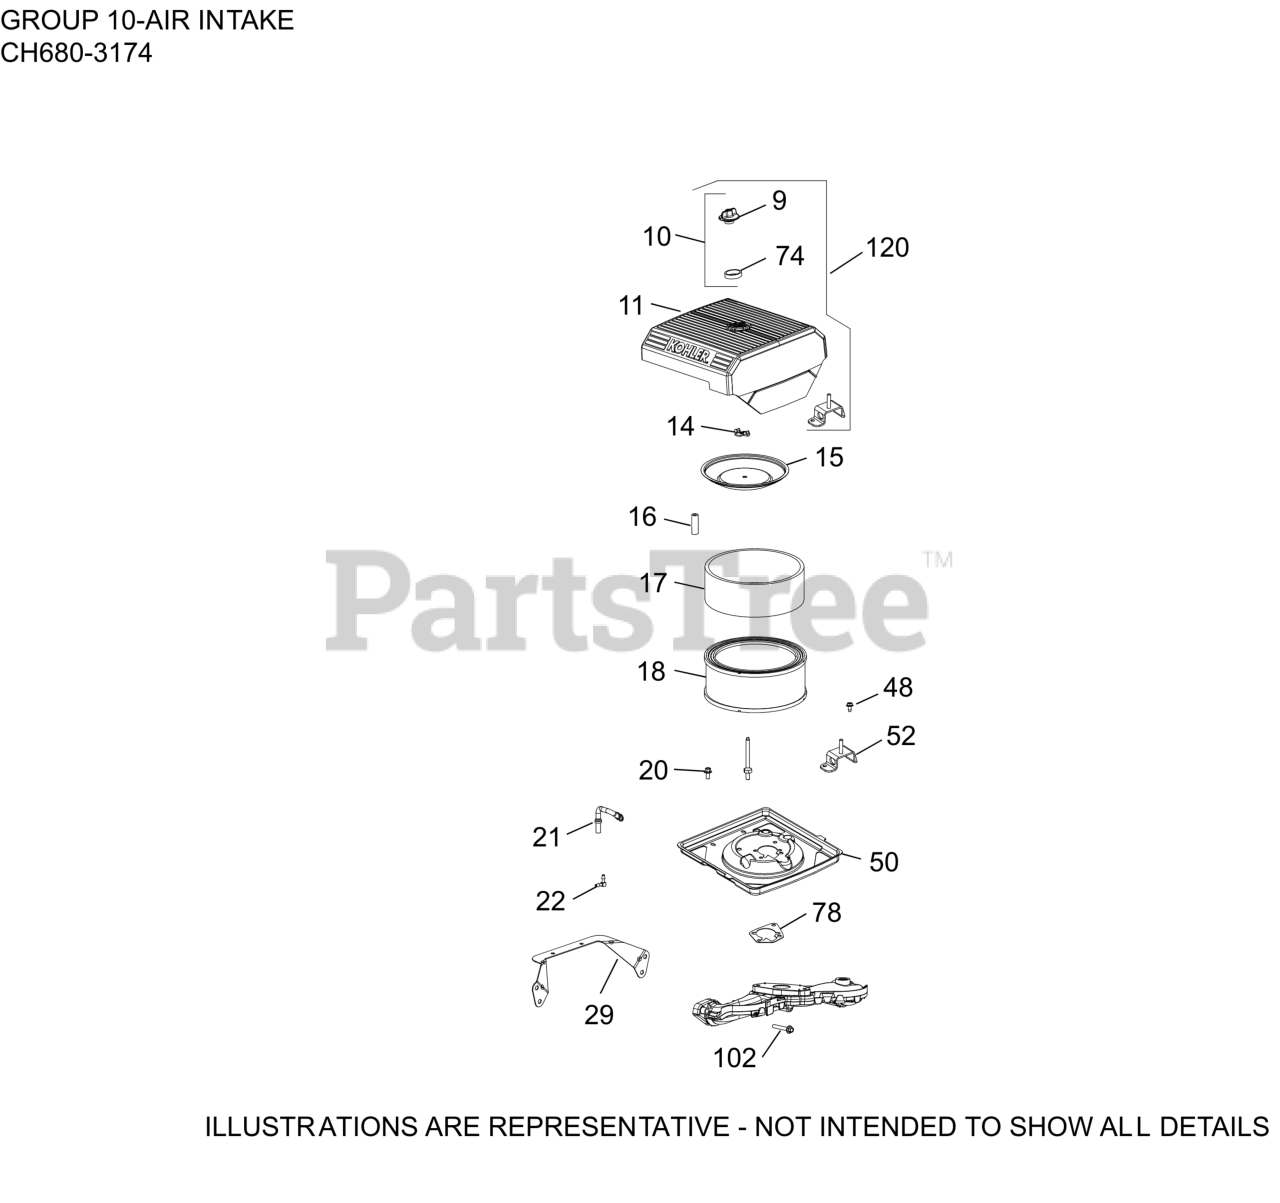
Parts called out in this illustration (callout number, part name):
9	KNOB, COVER
10	KIT, KNOB W/SEAL
11	COVER, AIR CLEANER
14	NUT, WING
15	COVER, INNER AIR CLEANER
16	SEAL BREATHER
17	PRE-CLEANER (HIGH)
18	AIR FILTER ELEMENT
20	SCREW, FLG THD FRM M6X1.0X16
21	HOSE, EVAP
22	CONNECTOR, EVAPORATIVE HOSE
29	AIR CLEANER BRACKET
45	SCREW, FLG M6X1.0X12
48	SCREW, THREAD FORMING
50	KIT, AIR CLEANER BASE
52	BRACKET, AIR CLEANER
78	GASKET, AIR CLEANER BASE
102	SCREW, FLG M6X1.0X40
120	KIT, AIR CLEANER COVER
